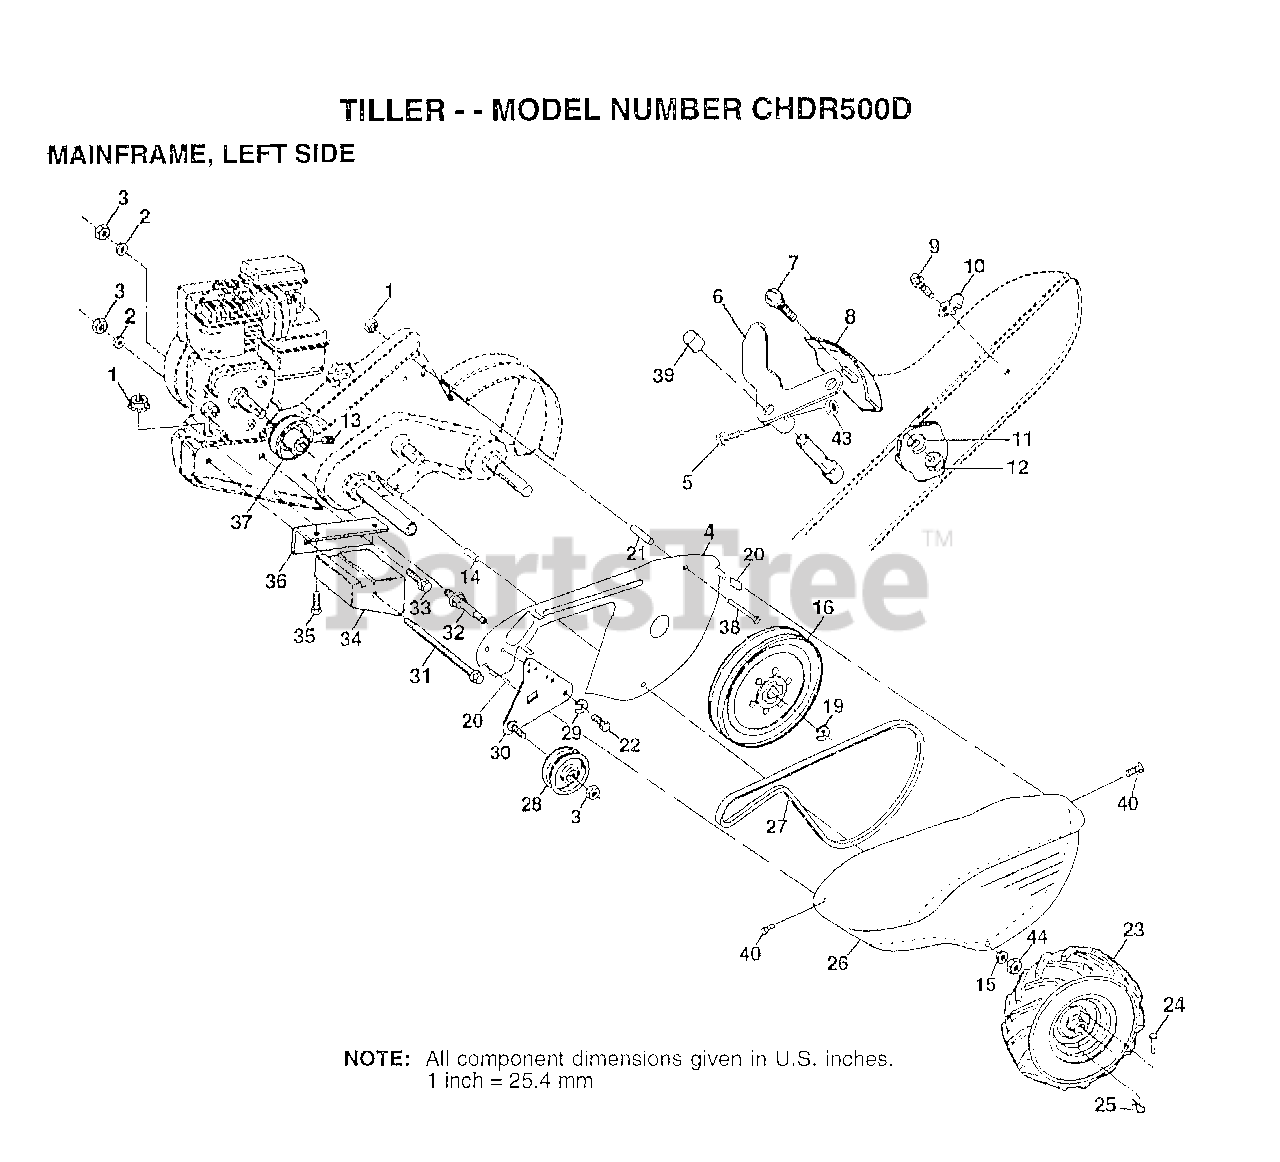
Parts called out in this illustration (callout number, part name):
2	LOCKWASHER
3	NUT.HEX.3/8-16UNC
4	SHIELD.INNER.BELT
5	"SCREW-LEVER,SHI"
6	LEVER ASM CRT
7	BOLT
8	PANEL TI
10	CONDIUT CLIP T
11	LOCKWASHER
13	SET SCREW
14	SPACER-SPLIT
15	WASHER
16	SHEAVE.TRANS.
20	NUT J CLIP #8
21	SPACER CRT
22	BOLT.FIN.HX.5/16-24X1/2
23	TIRE.CHV.13X5.0-6
24	RIVET.DRILL.1.75
25	RETAINER M
26	GUARD.BELT
27	BELT-V
28	PULLEY-IDLER TI
29	KLIP RING
30	BRACKET ASM IDLER
31	BOLT CRT
32	SHIFT ARM CRT
33	BOLT
34	COUNTERWEIGHT CRT
35	BOLT.HEX.5/16-1.5
36	BRACKET LH CRT
37	ENGINE PULLEY
39	CAP PLUNGER BLACK
40	SCREW HX WSH.HD#8-18X1/2
43	LOCKNUT
44	NUT
